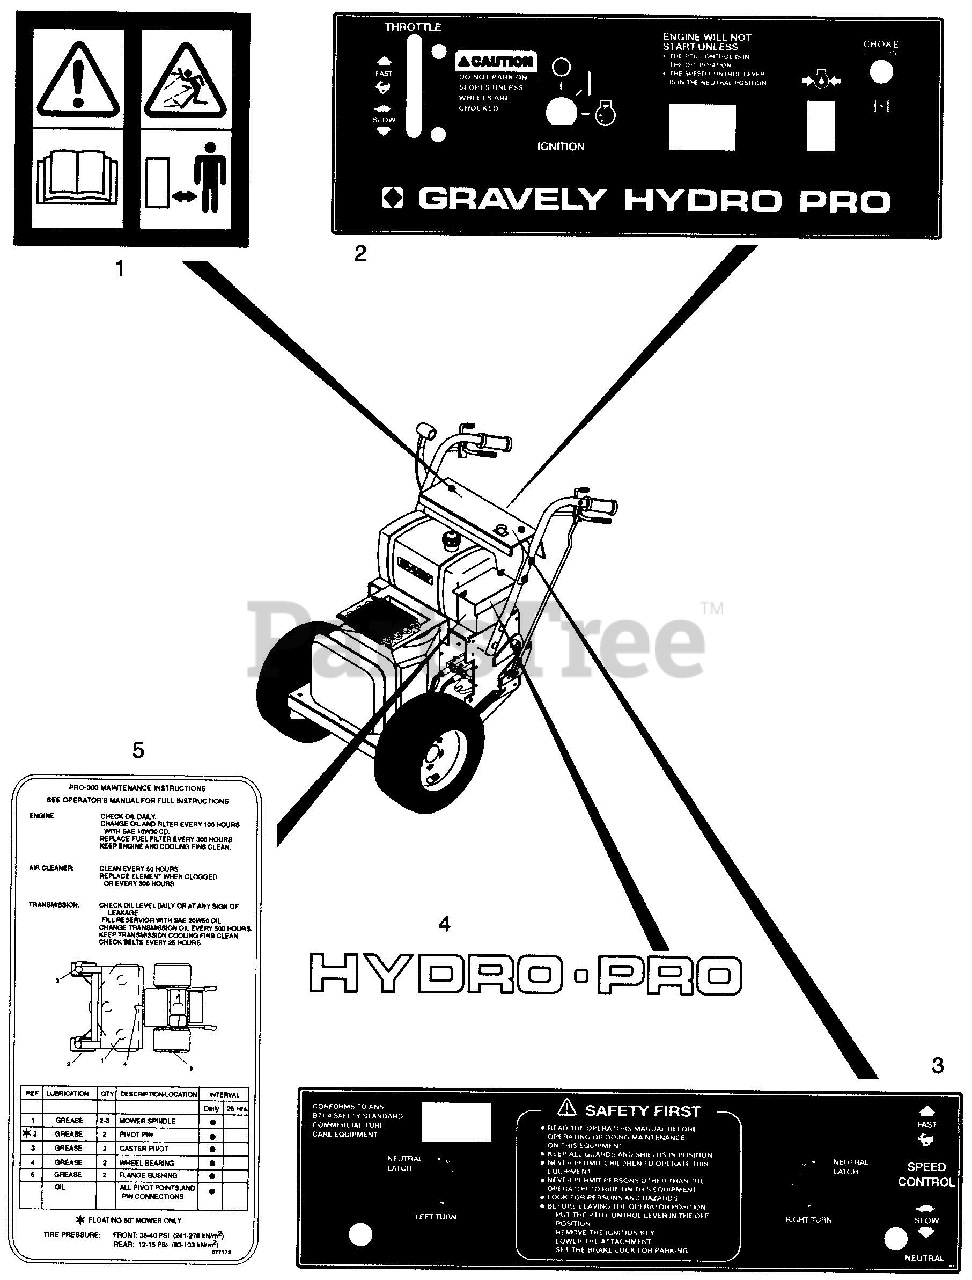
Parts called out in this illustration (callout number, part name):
1	Decal - WARNING Foreign
2	Decal - Pro-300 Instrument Panel
3	Decal - Pro-300 Instrument Panel
4	Decal - Hydro Pro
5	Decal - Pro-300 Maintenance
